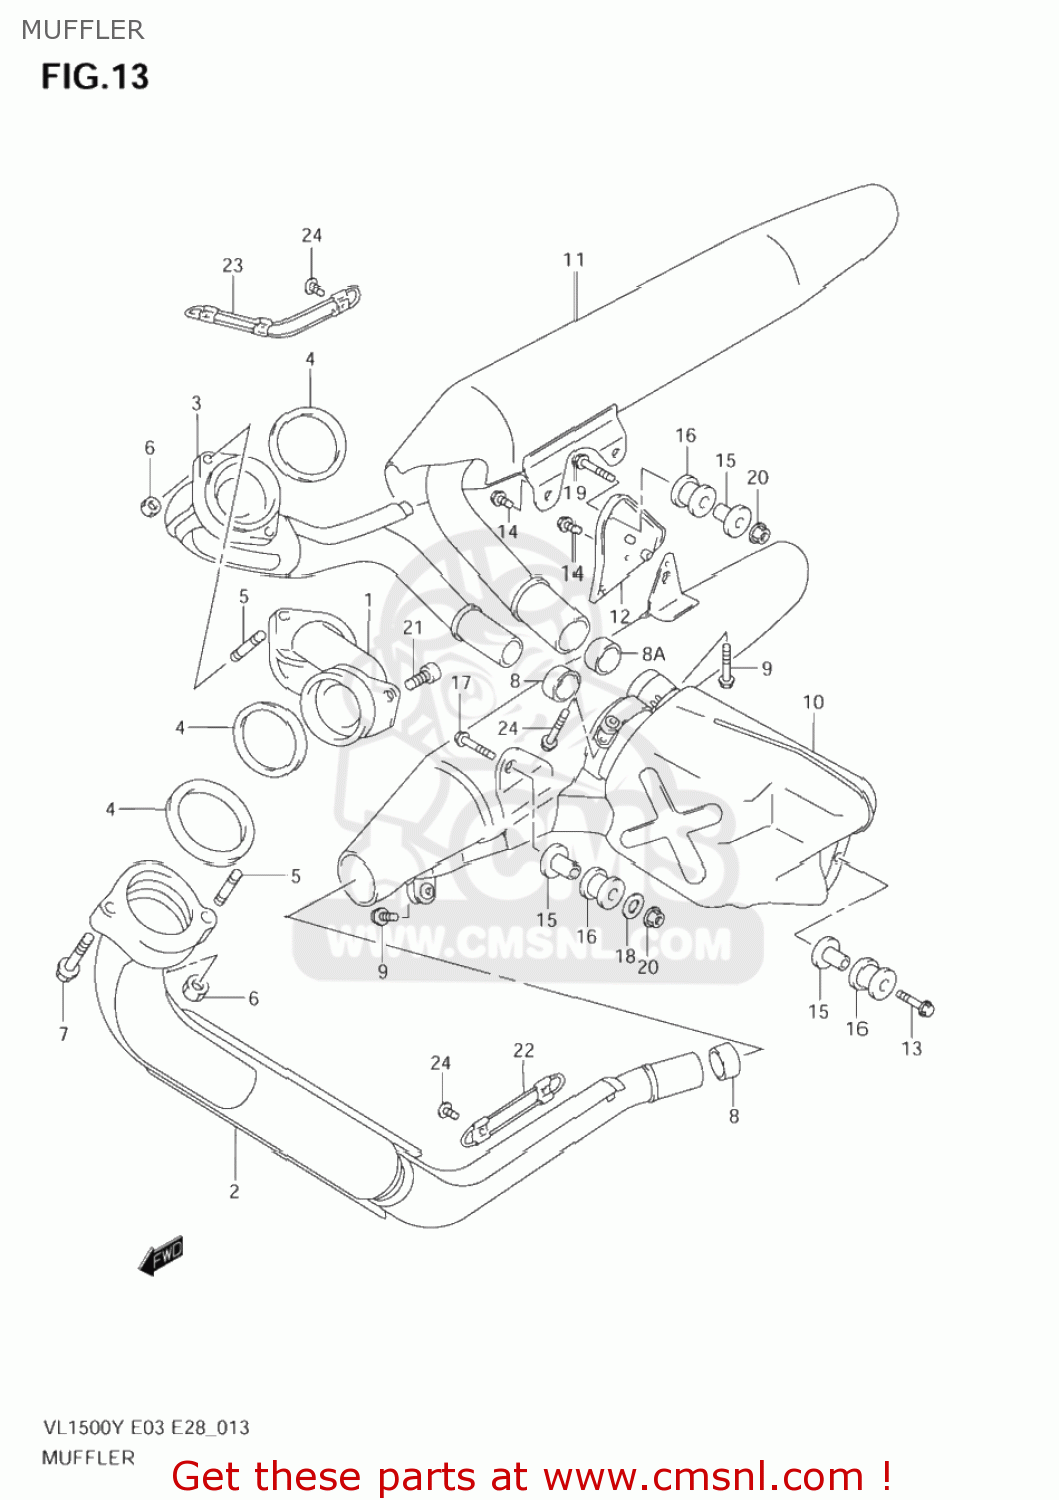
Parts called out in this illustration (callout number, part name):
1	MANIFOLD,EXHAUST RR
2	PIPE COMP,EXHAUST,RIGHT
3	PIPE,EXHAUST,L
4	GASKET,EXHAUST PIPE (NAS)
5	BOLT,STUD
6	NUT
7	BOLT(8X35)
8	CONNECTOR,MUFFLER
8A	CONNECTOR,MUFFLER
9	BOLT(8X33)
10	MUFFLER,R
11	BODY,MUFFLER,L
12	BRACKET,MUFFLER SUPPORT
13	BOLT 8X45
14	BOLT(8X14)
15	SPACER(8.6X12X27.1)
16	CUSHION
17	BOLT
18	WASHER (8.5X33X1.6)
19	BOLT
20	NUT
21	BOLT
22	GUARD,EXH,R
23	GUARD,EXH,L
24	SCREW(6X10)
